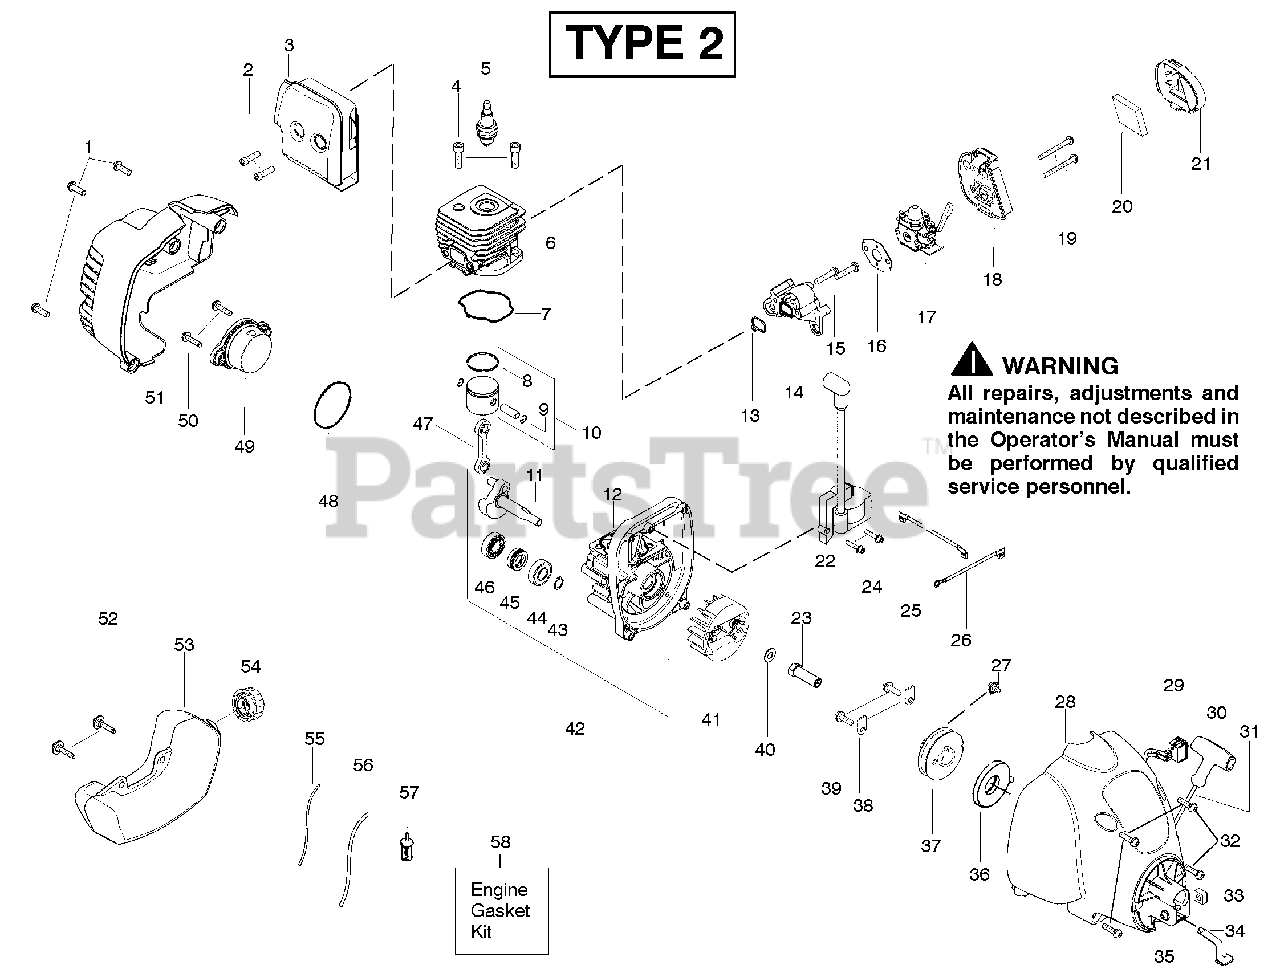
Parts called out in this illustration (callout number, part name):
3	Assy-Muffler/Shield
4	Screw-Cylinder
5	Spark Plug (RCJ 6Y)
7	Seal-Cylinder (kit)
8	Piston Ring
9	Retainer-Piston Pin
10	Kit - Piston
11	Assy-Crankshaft
12	Assy-Crankcase
13	Seal-Cyl/Carb.(kit)
14	Adapter-Carb.
16	Gasket-Carb. (kit)
17	Kit-Carb. Zama (C1U-W18)
17	Kit-Carb. Walbro ( WT-669)
18	Air Box
20	Foam-Air Filter
21	Cover-Air Box
22	Ignition Module
23	Coupling-Drive
25	Assy-Leadwire
26	Assy-Ground Wire
28	Assy.-Fan Hsg
30	Handle-Starter
36	Spring-Starter
37	Kit-Pulley-Starter
38	Retainer-Pulley
41	Assy-Flywheel
42	Assy-C'case & C'shaft
43	Retain. Ring-C'shaft
44	Outer Bearing
46	Inner Bearing
47	Assy-Connecting Rod
48	O-Ring-C'case (kit)
49	Assy-Plug
51	Shroud-Rear Green
51	Shroud-Rear Black
52	Retainer-Tank
53	Assy-Fuel Tank
54	Assy-Fuel Cap
55	Kit-Fuel Line (Small)
56	Kit-Fuel Line (Large)
57	Assy-Fuel Pickup
58	Kit-Engine Gasket
